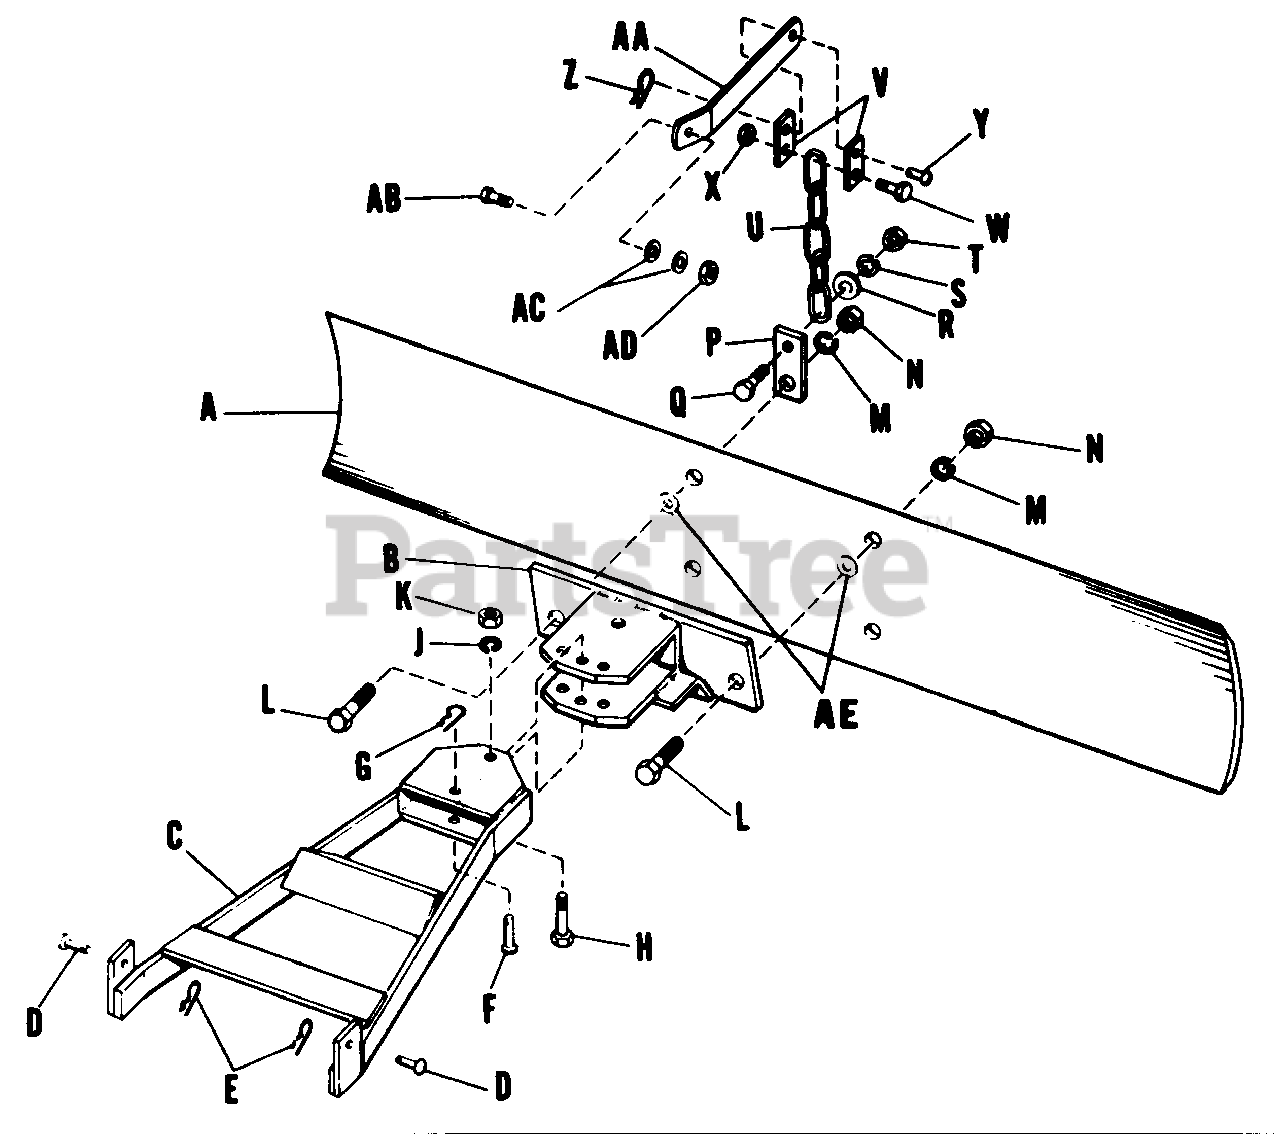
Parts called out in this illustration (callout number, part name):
A	Blade, Grader, 42"
B	Hitch Assembly
C	Draw Par Assembly
D	Pin
E	Spring Clip
G	Spring Clip
H	Capscrew, Hex Head, 5/8"-11 NC x 3" lg.
J	Lockwasher, 5/8"
K	Nut, Hex. Full. 5/8"-11 NC
L	Capscrew, Hex Head, 5/8"-11 NC x 2" lg
M	Lockwasher, 5/8"
N	Nut, Hex, Full, 5/8"-11 NC
Q	Capscrew, Hex Head, 3/8"-16 NC x 1-1/4" lg.
R	Plain Washer, 3/8"
S	Lock Washer, 3/8"
T	Nut, Hex, Full, 3/8"-16 NC
U	Chain
W	Capscrew, Hex Head, 3/8"-16 NC x 1-1/4" lg.
X	Nut, Hex, Full, Lock, 3/8"-16 NC
Z	Spring Clip
AB	Capscrew, Hex Head, 3/8"-16 NC x 1-1/4" lg.
AC	Plain Washer, 3/8"
AD	Nut, Hex, Full, Lock, 3/8"-16 NC
AE	Flat Washer, 1-1/16"
